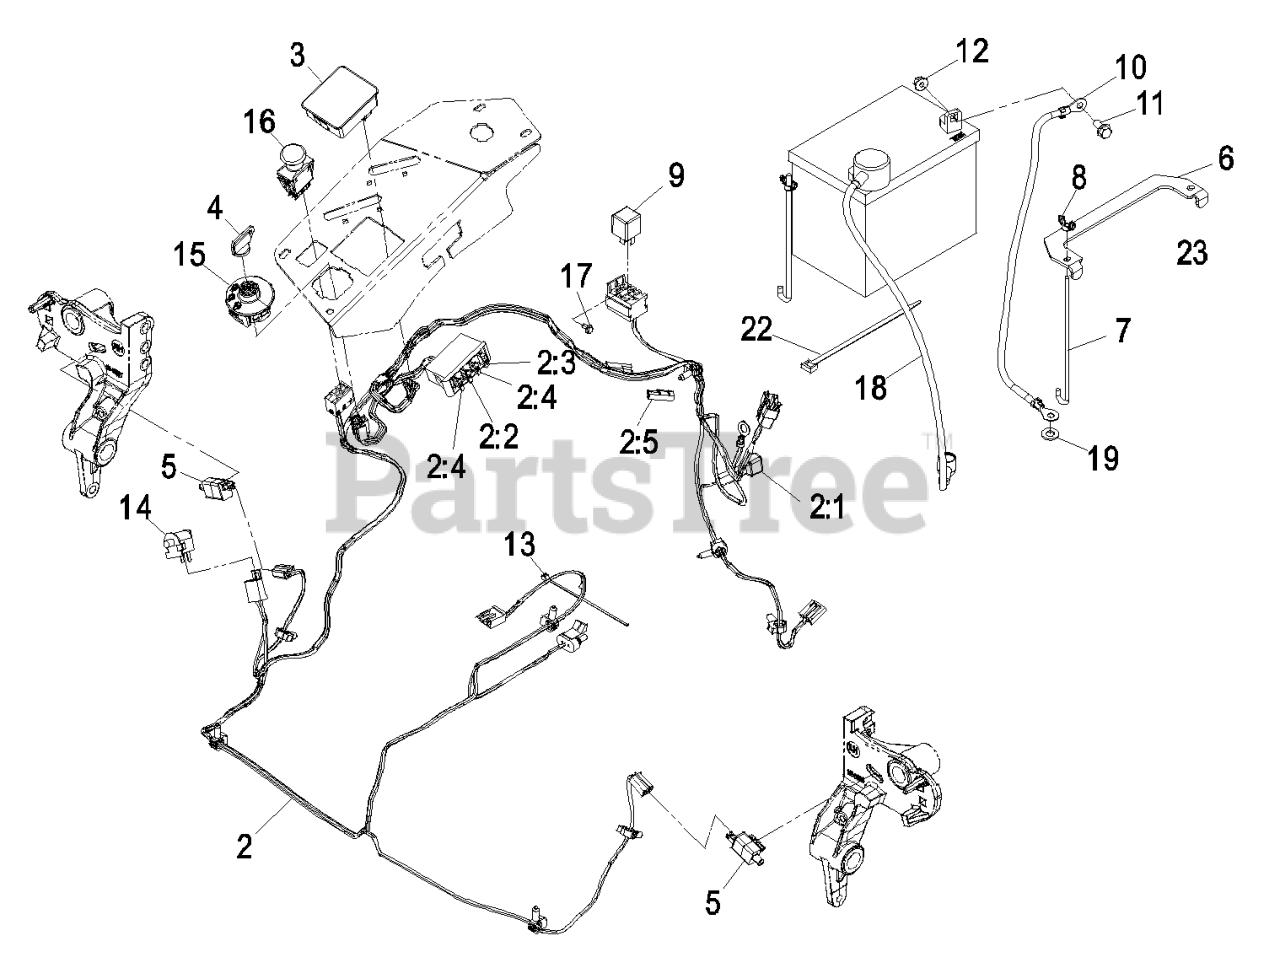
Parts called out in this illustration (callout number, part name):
2:2	FUSE-BLADE, 10 AMP
2:3	FUSE-BLADE, 15 AMP
2:4	FUSE-BLADE, 25 AMP
2:5	CAP-PLUG
4	KEYS-IGNITION (SPARE PAIR
6	STRAP-TIE DOWN, BATTERY
7	BOLT-HOLDDOWN
8	WINGNUT
10	CABLE-BATTERY, NEGATIVE
11	SCREW-HHF
12	NUT-HF, NI
13	TIE-CABLE
14	SWITCH-BAIL
16	SWITCH-PTO, 10 AMP
17	SCREW-HWH
18	CABLE-BATTERY, POSITIVE
19	WASHER-FLAT
22	TIE-PLASTIC
